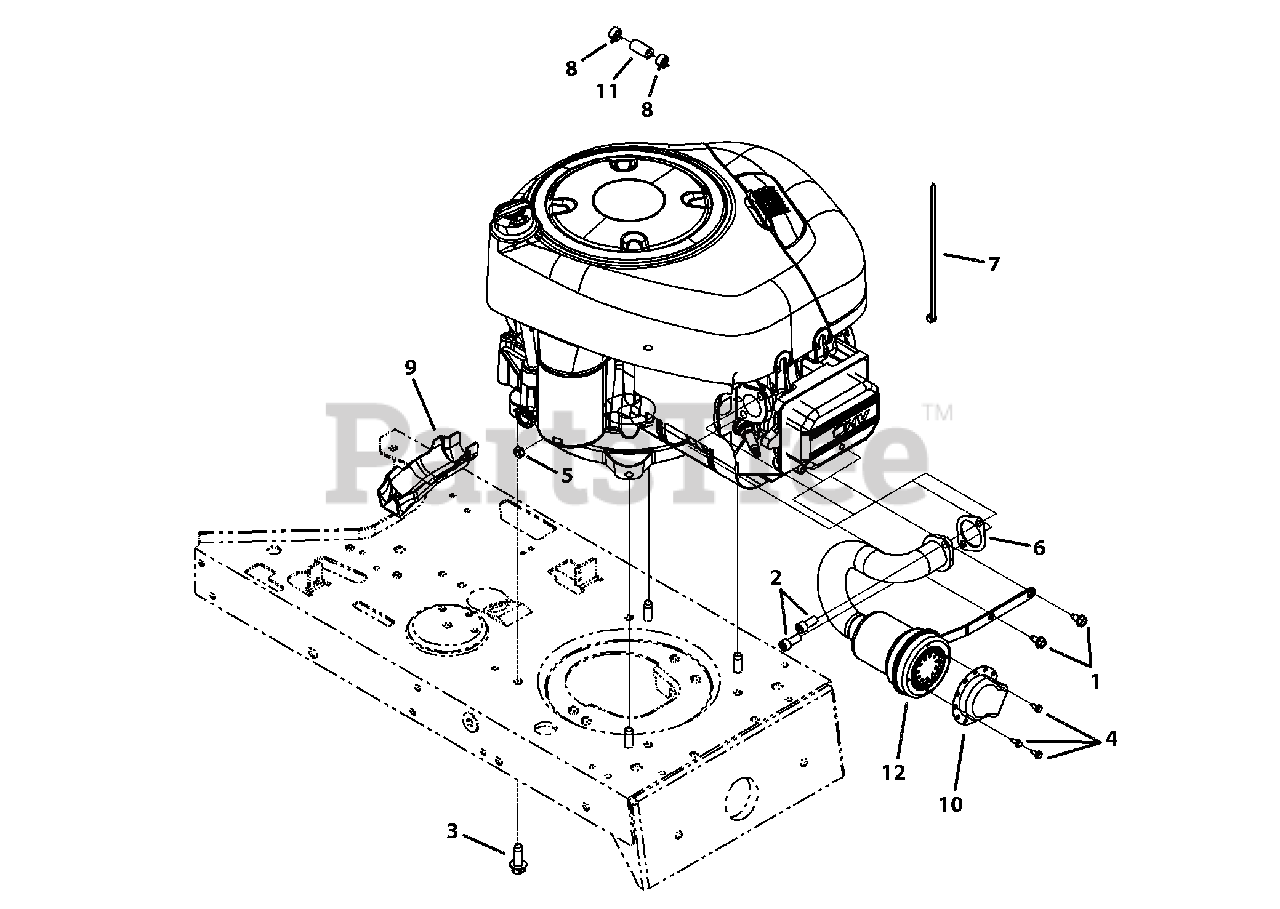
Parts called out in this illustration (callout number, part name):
1	Screw, 1/4-20 x .500
2	Socket Screw, 5/16-18 x .750
3	Screw, 3/8-16 x 1.000
4	Screw, 8-18 x .500
5	Sems Nut, 1/4-20
6	Exhaust Gasket, 10 HP Briggs
7	Cable Tie
8	Hose Clamp, .490 Diameter
9	Oil Drain Sleeve
10	Muffler Deflector
11	Fuel Hose, Low Permeation
12	Muffler
